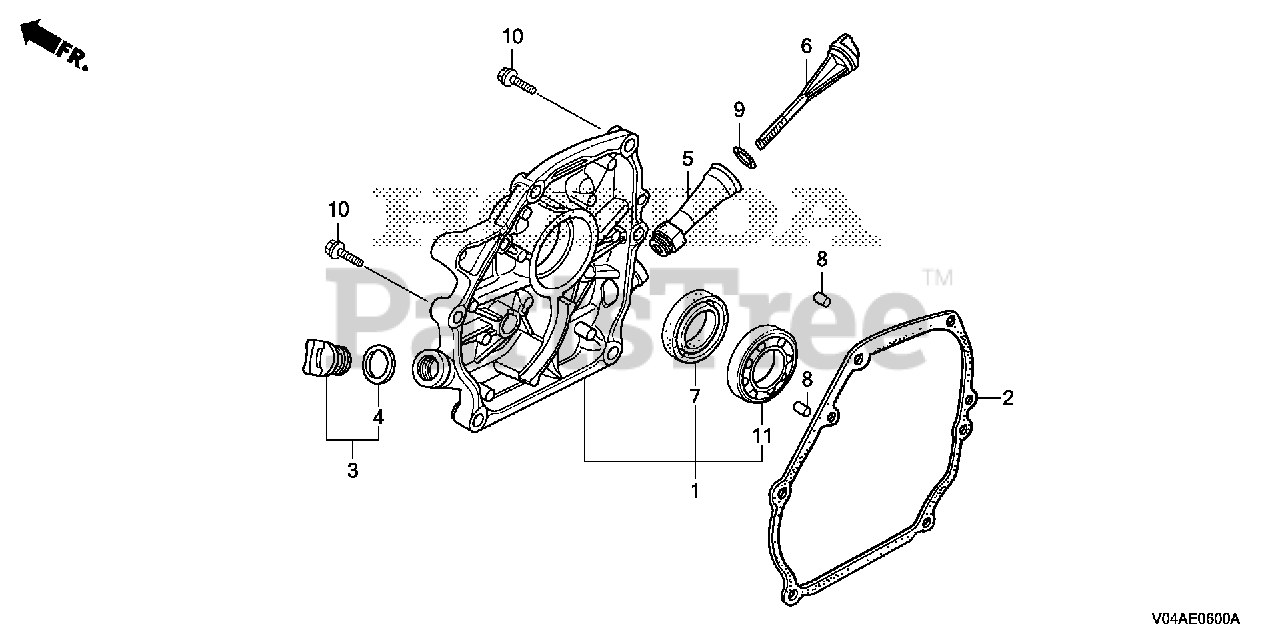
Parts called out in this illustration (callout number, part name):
1	COVER ASSY., CRANKCASE
2	GASKET, CASE COVER (NON-ASBESTOS)
3	CAP ASSY., OIL FILLER
4	GASKET, OIL FILLER CAP
5	PIPE, OIL FILLER
6	DIPSTICK, OIL
7	OIL SEAL (25X41X6)
8	PIN A, DOWEL (8X14)
9	O-RING (23X2.8)
10	BOLT, FLANGE (8X32)
11	BEARING, RADIAL BALL (6205)
